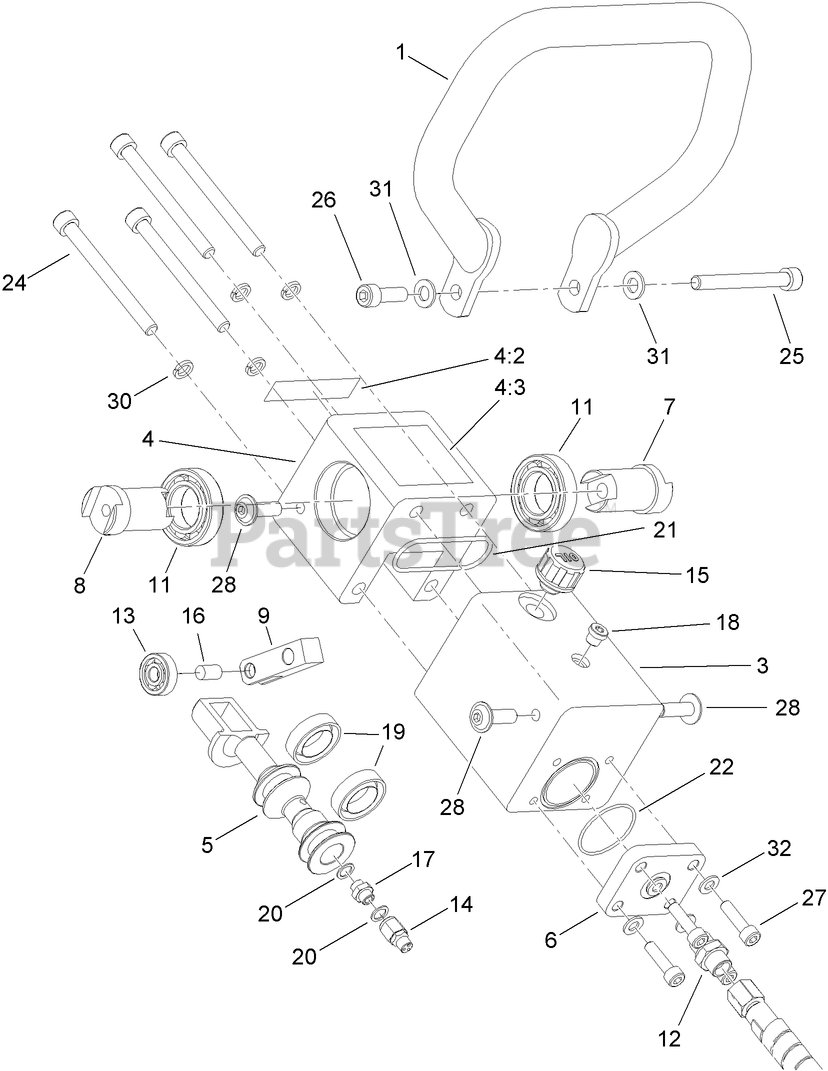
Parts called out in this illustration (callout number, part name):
1	HANDLE
3	BODY-MANIFOLD (I)
4	MANIFOLD ASM
4:2	DECAL-CAUTION
4:3	DECAL-OPERATION
5	PISTION
6	PLATE-SEALING
7	PIVOT I
8	PIVOT I I
11	BEARING
12	SOCKET
13	BEARING
14	VALVE-DIRECT
17	COUPING
19	PACKING
21	O-RING
22	O-RING
30	WASHER
31	WASHER
32	WASHER
